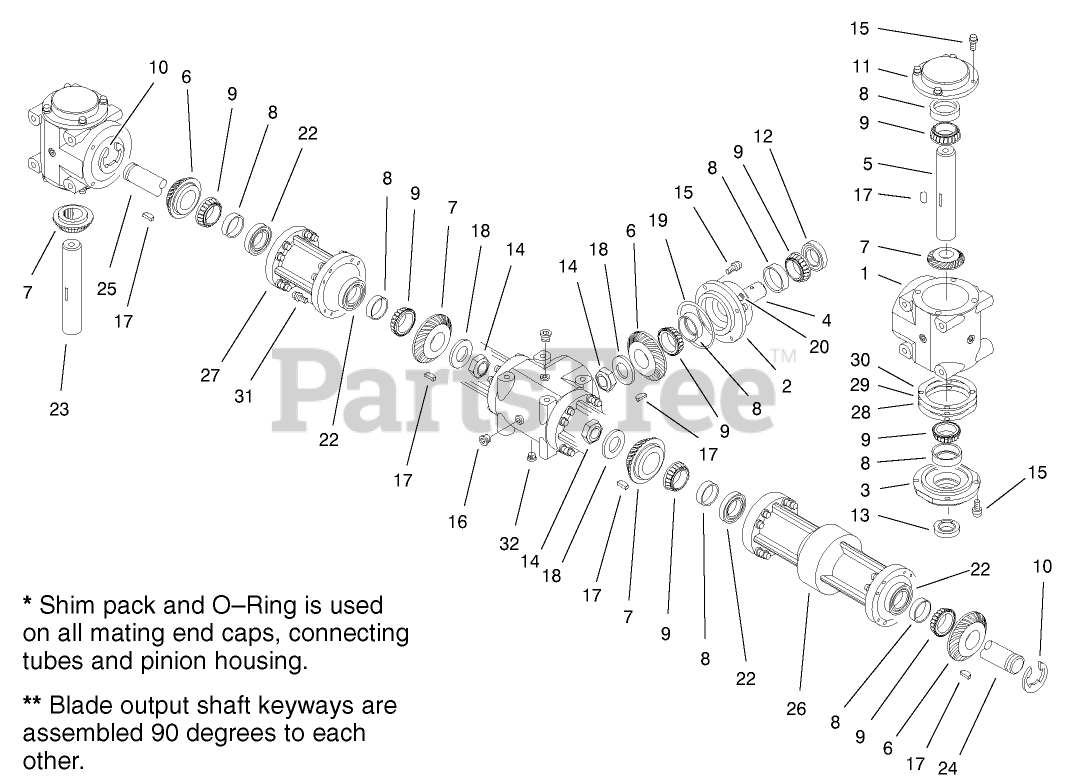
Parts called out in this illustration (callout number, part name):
2	HOUSING - PINION
3	CAP-END, OPEN
4	SHAFT - INPUT, KEYED
5	SHAFT - CROSS, A/D
6	GEAR - 27 TOOTH
7	GEAR - 29 TOOTH
8	Bearing-Cup
9	Bearing-Cone
10	CLIP-RETAINING
11	CAP-END, CLOSED
13	SEAL
14	NUT-JAM
17	KEY-WOODRUFF
18	WASHER
19	O-RING
23	SHAFT - CROSS, B/D
24	SHAFT - CONNECTING, LONG
25	SHAFT - CONNECTING, SHORT
26	FLANGE - CONNECTING, LONG
27	FLANGE - CONNECTING, SHORT
28	SHIM-BROWN, .010IN
29	SHIM-BLUE, .005IN
30	SHIM-GREEN, .003IN
32	PLUG-MAGNETIC
